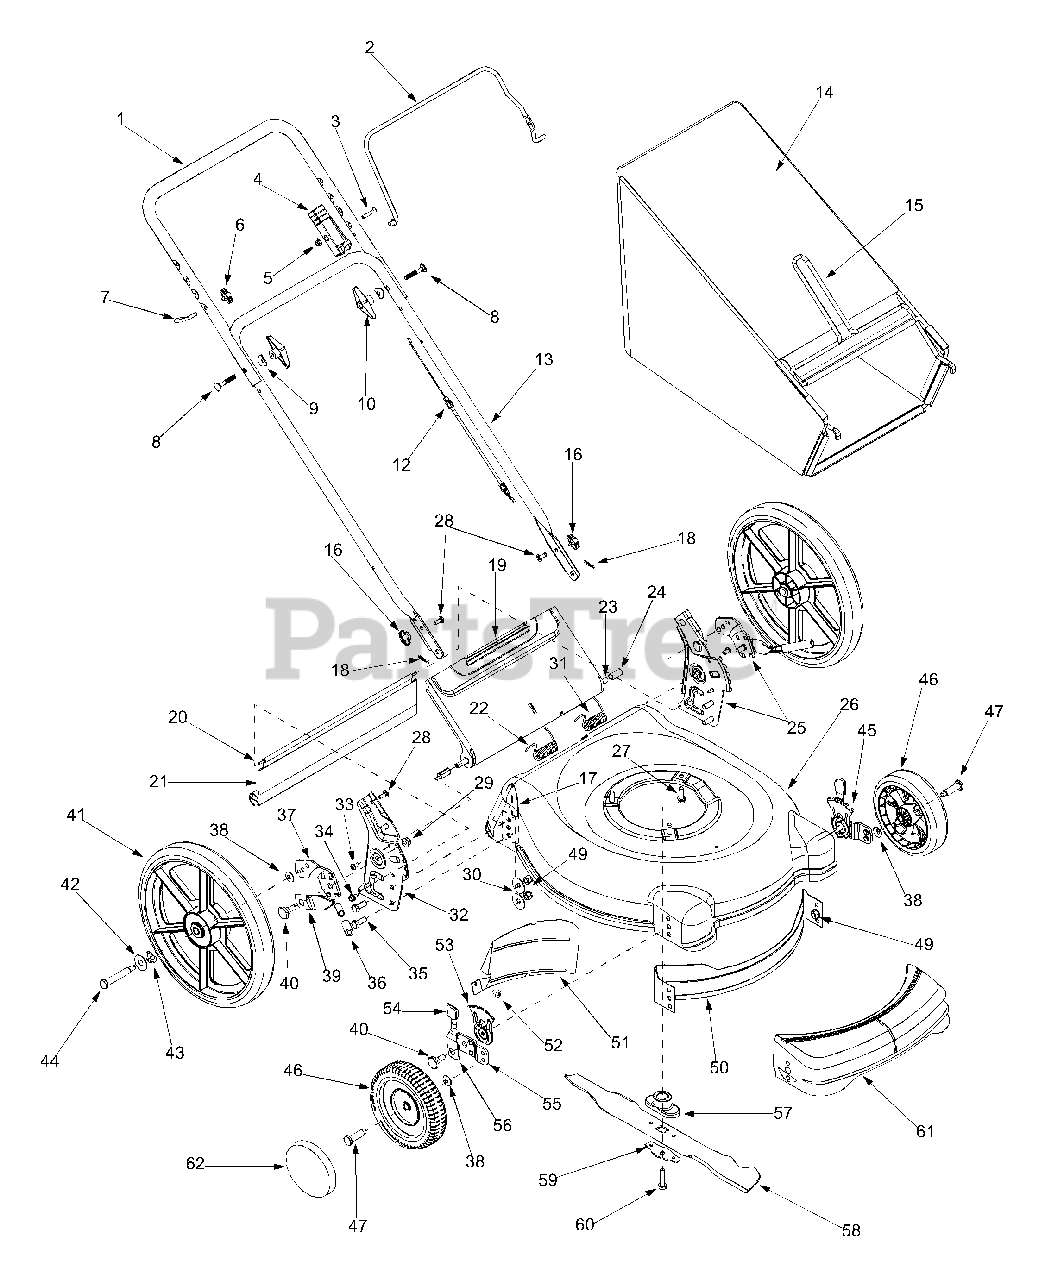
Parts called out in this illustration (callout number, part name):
3	C-Sunk Screw 1/4-20 x 1.3"
4	Throttle Housing
5	Hex Lock Nut 1/4-20
6	Handle Knob
7	Rope Guide
8	Carriage Bolt 5/16-18 x 2"
9	Shoulder Washer .320 ID x .930 OD
10	Wing Nut
12	Blade Control Cable 40.5"
14	Grass Bag
16	Handle Knob
18	Hairpin Clip
19	Grass Bag Door
20	Wire Rod
21	Trail shield
22	Door Spring, RH
23	Chute Door Pivot Rod
24	Spacer .390 O.D. x .810 I.D. x .95"
25	Handle Brkt Ass'y, w/Adj - LH
27	Hex Washer Screw 3/8-16 x 1.0
28	Hex Carriage Screw 1/4-20
29	Flange Lock Nut 3/8-16
30	Bell Washer .390 ID x .380 OD
31	Door Spring, LH
32	Handle Bracket Assembly - RH
33	Machine Screw 1/4-20 x .500
34	Hex Washer Screw 1/4-14 x .625
35	Hex Cap Screw 3/8-16 x .75
36	Foam Grip
37	Pivot Bar - RH
38	Spring Washer .375 ID x .870 OD
39	Spring Lever
40	Shoulder Screw
41	Rear Wheel Assembly 14 x 2.1
42	Flat Washer .510 ID x 1.00 OD
43	Wave Washer .500 ID x 1.0 OD
44	Shoulder Screw
45	Front Height Adjuster - RH
46	Front Wheel Assembly 8 x 2.1
47	Shoulder Bolt
49	Flange Lock Nut 3/8-16
52	Tap Screw 1/4-14 x .625.
53	Height Adjustment Plate
54	Height Adjustment Knob
56	Spring Lever
57	Blade Adapter
58	21" Mulching
59	Blade Bell Support
60	Hex Cap Screw 3/8-24 x 1.5
61	Front End Cover
62	Hub Cap
